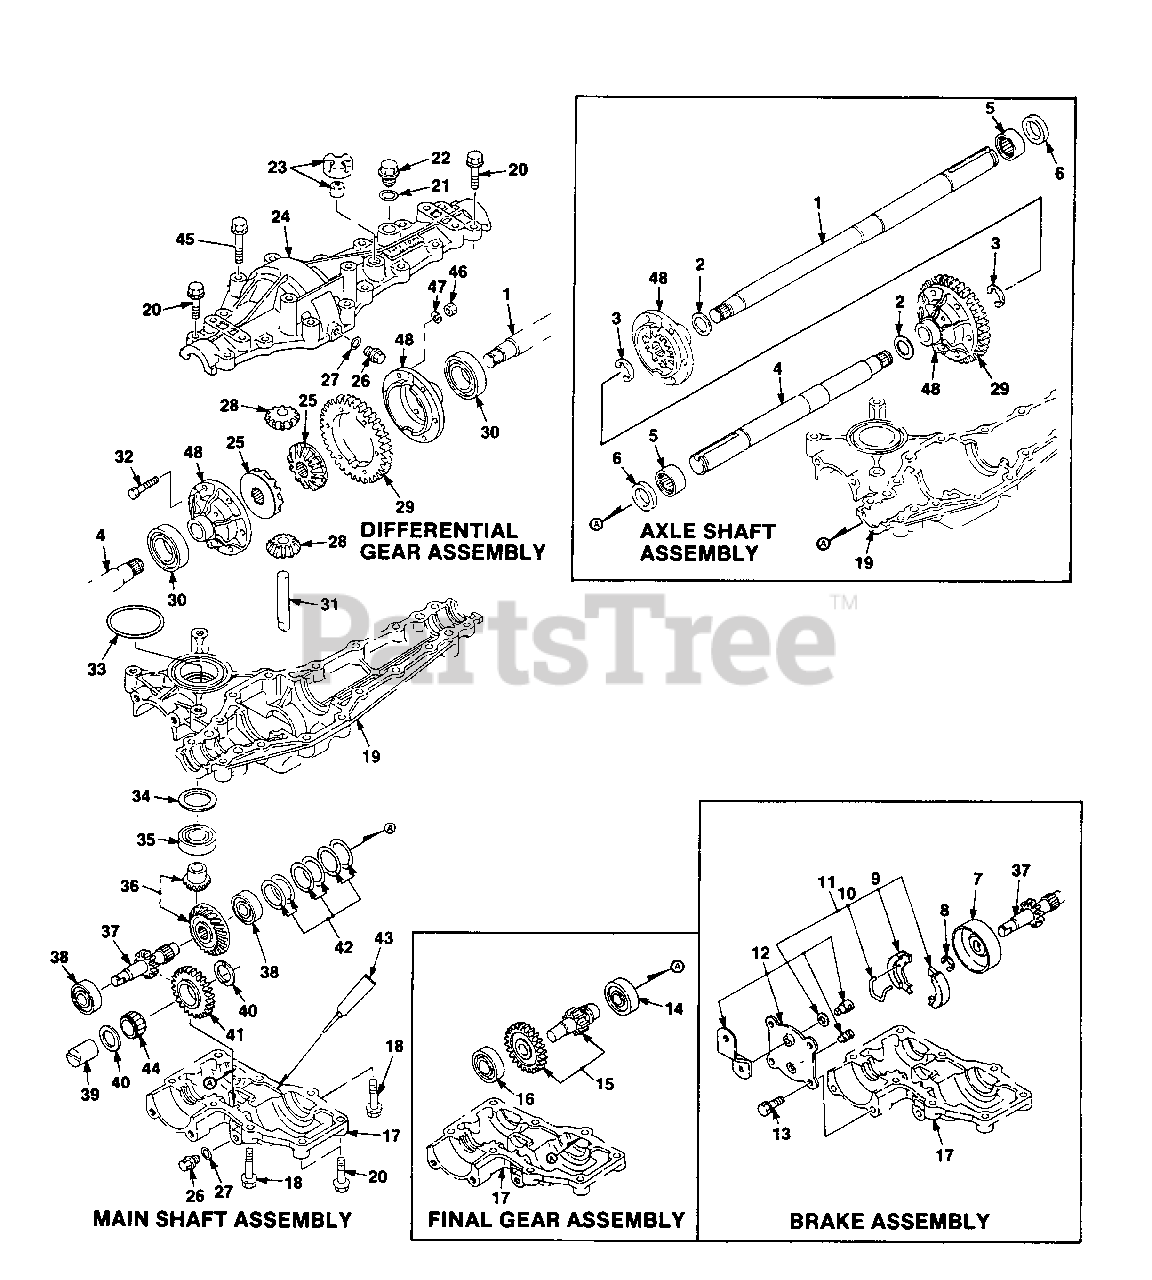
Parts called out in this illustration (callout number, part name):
1	AXLE & SHAFT (R)
2	WASHER- (20 x 29.5 x 2)
3	RING- (15)
4	AXLE- Shaft
7	DRUM- Brake
8	RING- (10)
9	SHOE- Brake
11	BRAKE- Assy (CB-1)
12	BRAKE COVER ASSY.
13	BOLT- (w/washer) (8 x 20)
14	BEARING (6203)
15	FINAL PINION ASSY.
16	BEARING- (6302)
17	CASE- Lower
18	SCREW- Tapping (8 x 35)
19	MISSION CASE
20	SCREW- Tapping (8 x 30)
21	PACKING- (P16)
22	PLUG- (14)
23	VENT VALVE ASSY.
24	UPPER CASE
25	GEAR- Differential
28	PINION- Differiential
29	GEAR- Final (43)
30	BEARING- (6006)
31	SHAFT- Diff. Pinion
32	BOLT- (6 x 30)
33	PACKING- (G60)
34	WASHER- (.30 x 42 x 2)
35	BEARING- (6004)
36	MOTOR GEAR ASSY.
37	MAIN SHAFT
38	BEARING- (6202)
39	SHAFT- Idle
40	WASHER- Thrust
41	GEAR- (24)
42	SHIM- ASSY.
44	NEEDLE- (20 x 26 x 12)
45	SCREW- Tapping (8 x 45)
